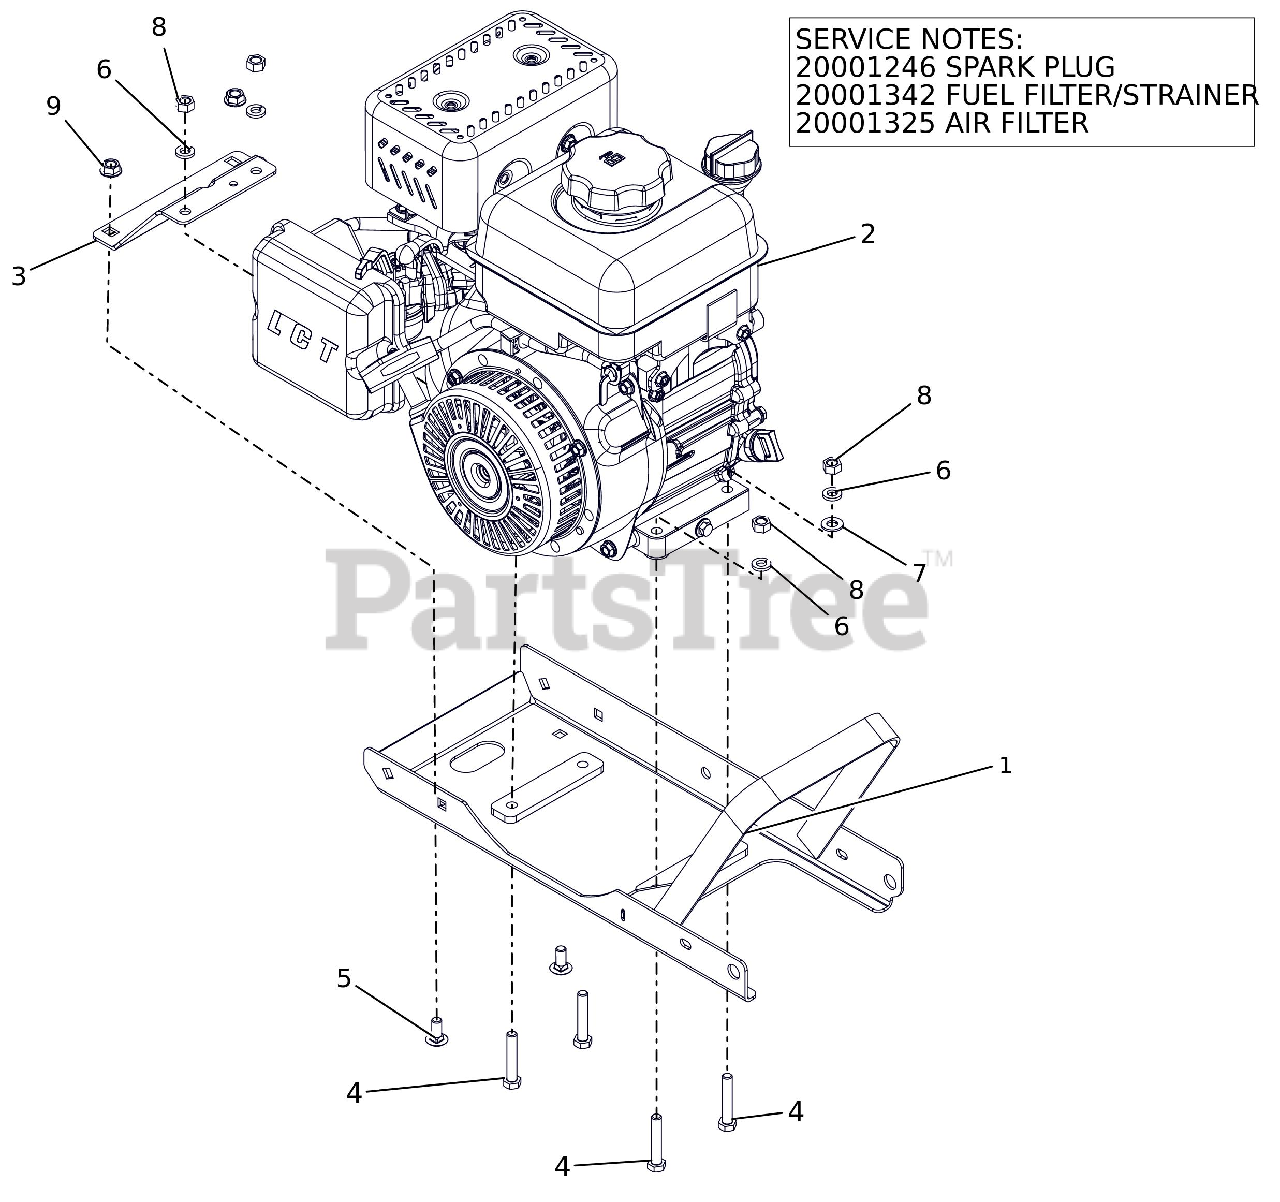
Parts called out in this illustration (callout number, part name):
1	FRAME,EDGER
2	ENGINE, LCT-136
2	SPARK PLUG, ARIENS AX
2	FUEL TANK STRAINER
2	AIR FILTER ASSY - COMPLETE
3	BRACKET, REINFORCEMENT
4	@BLT-HEX .31-18X1.75 GR5 YWZC
5	@BLT-RDHDSQNK .31-18X.75 G5YZ
6	WSHR-LK .312X.097 HVY YWZC
7	@WSHR-FL-STL.344X.688X.065YWZC
8	@NUT-HEX .31-18 YWZC
9	@NUT-LK-TOP-FLG .31-18 YWZC
